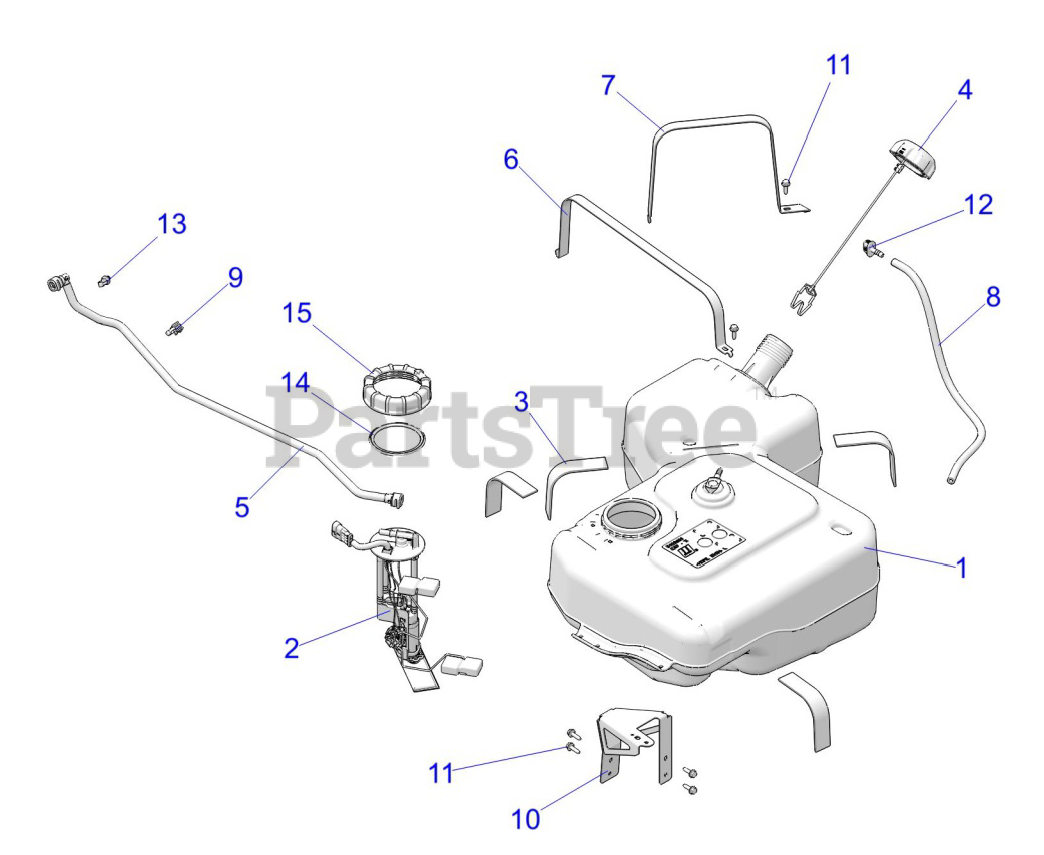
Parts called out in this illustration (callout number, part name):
1	ASM-FUEL TANK
2	ASM-FUEL PUMP
3	PAD- BATTERY
4	CAP-GAS TANK- TETHER
5	ASM-FUEL LINE
6	BRKT-TANK-STRAP-INSIDE-GALV
7	BRKT-TANK-STRAP-OUTSIDE-GALV
8	FUEL LINE-54 CENTIMETERS
9	CLIP-EDGE-SIDE W/STRAP
10	BRKT-FUEL TANK-SUPPORT-BLK
11	SCR-TXTH-M6X1.0X25 RIE
12	FITTING-VENT LINE
13	CLIP-ROUTING
15	NUT- JAM
